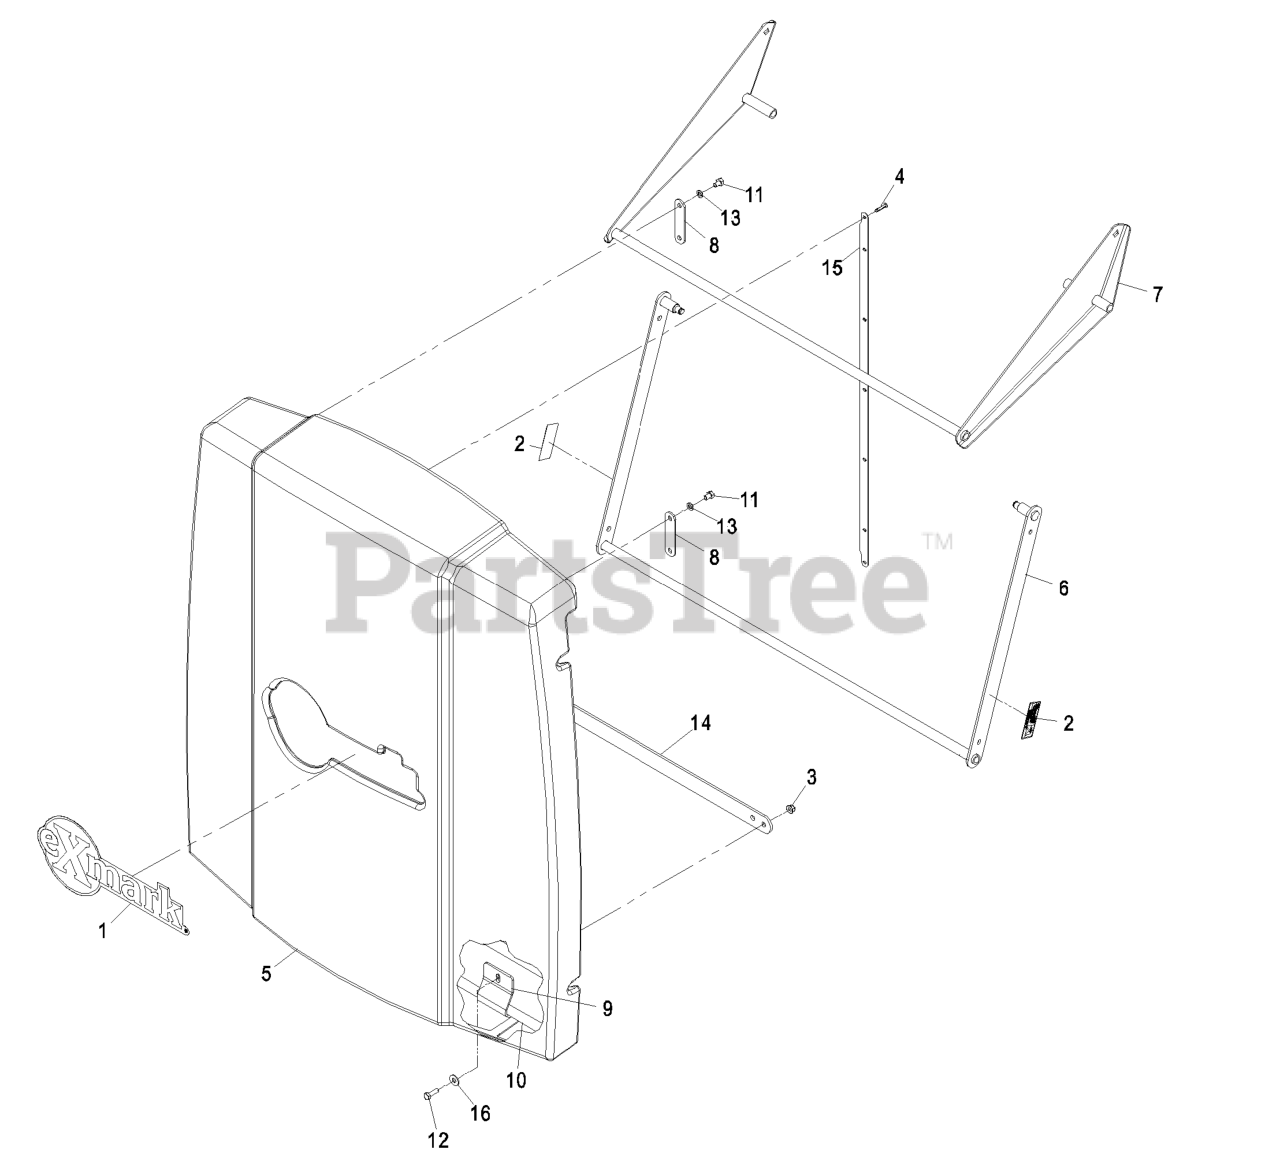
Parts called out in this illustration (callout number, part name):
1	DECAL,EXMARK LOGO
2	DECAL-PINCH POINT
3	NUT-HF, NI
5	Asm, Door W/Decal
7	WLD,FR DOOR UPR PVT
8	STRAP,FR DOOR PIVOT
9	PLATE,FRUVD DOOR LATCH
10	TUBE,FRUVD DOOR
11	SCREW-HH
12	SCREW-HH
13	WASHER-LOCK
14	PLATE,FRUVD DOOR REINF
15	ASM,FRUVD DR BRACE SVC
16	WASHER-FLAT
